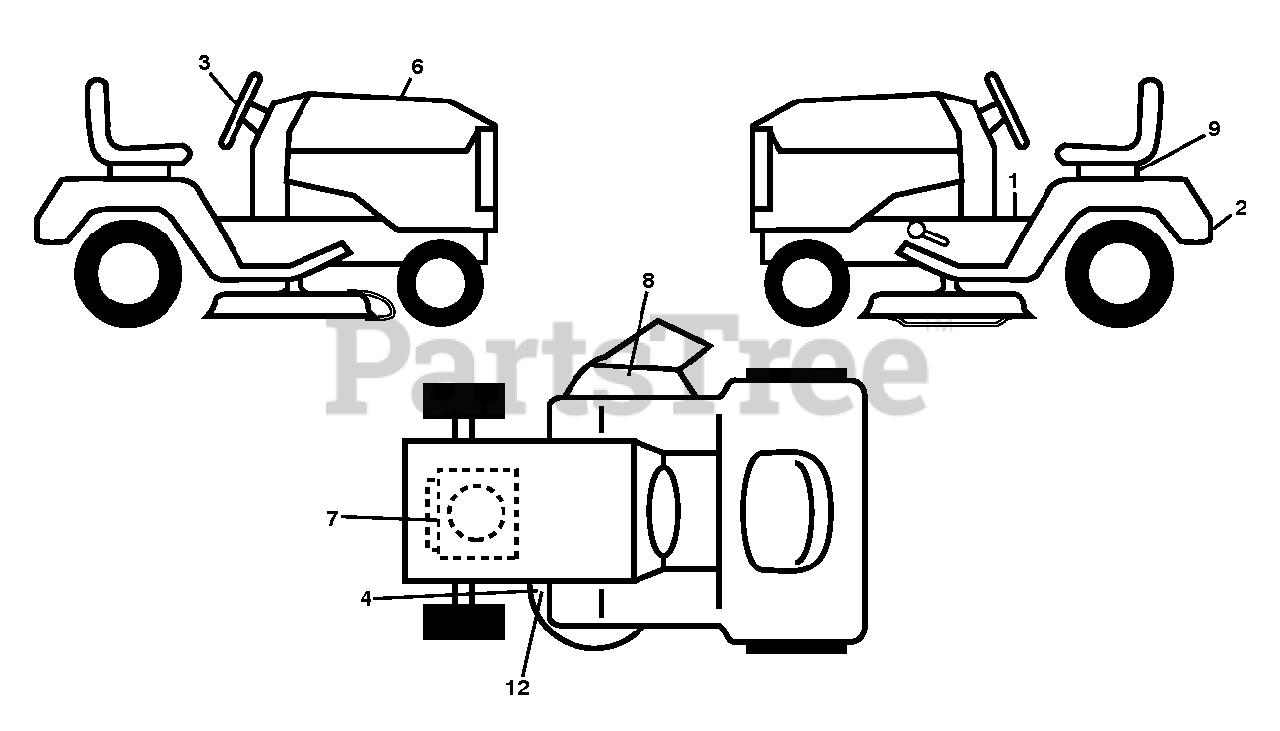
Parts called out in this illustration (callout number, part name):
1	Fender Warning Decal, English
4	DECAL DECK, STEEL REINFORCED
6	DECL.RPL.BSM40.INTK.TLW.42.K46
7	Decal, Engine BS 20INTK DOM 381707
8	DECAL, DECK DEFLECTOR, WARNING
9	DECAL BTRY SYMBOLS
